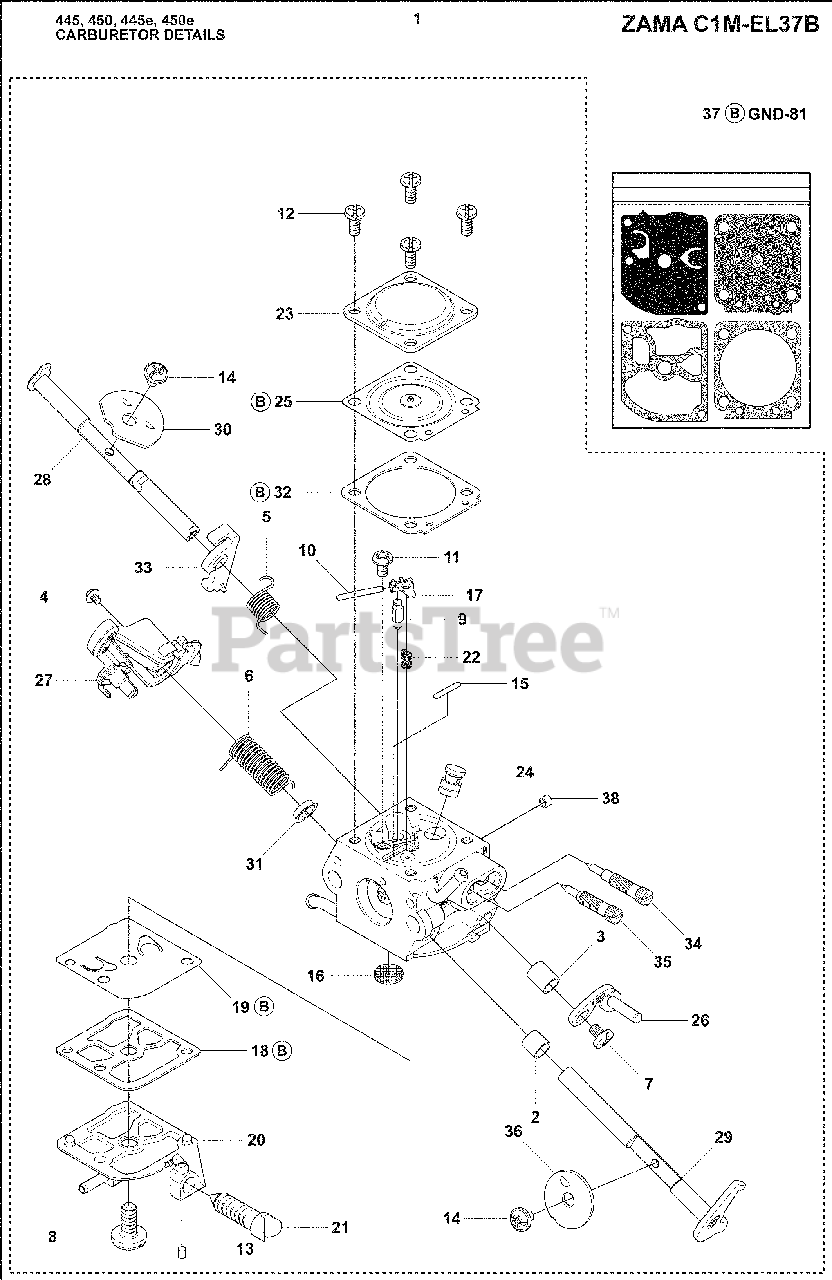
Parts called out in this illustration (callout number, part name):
1	Carburetor
9	Inlet Needle
10	Pin
19	Pump Diaphragm
27	Throttle Lever
28	Shaft Assembly
29	Shaft Assembly
37	B = Set of Gaskets
